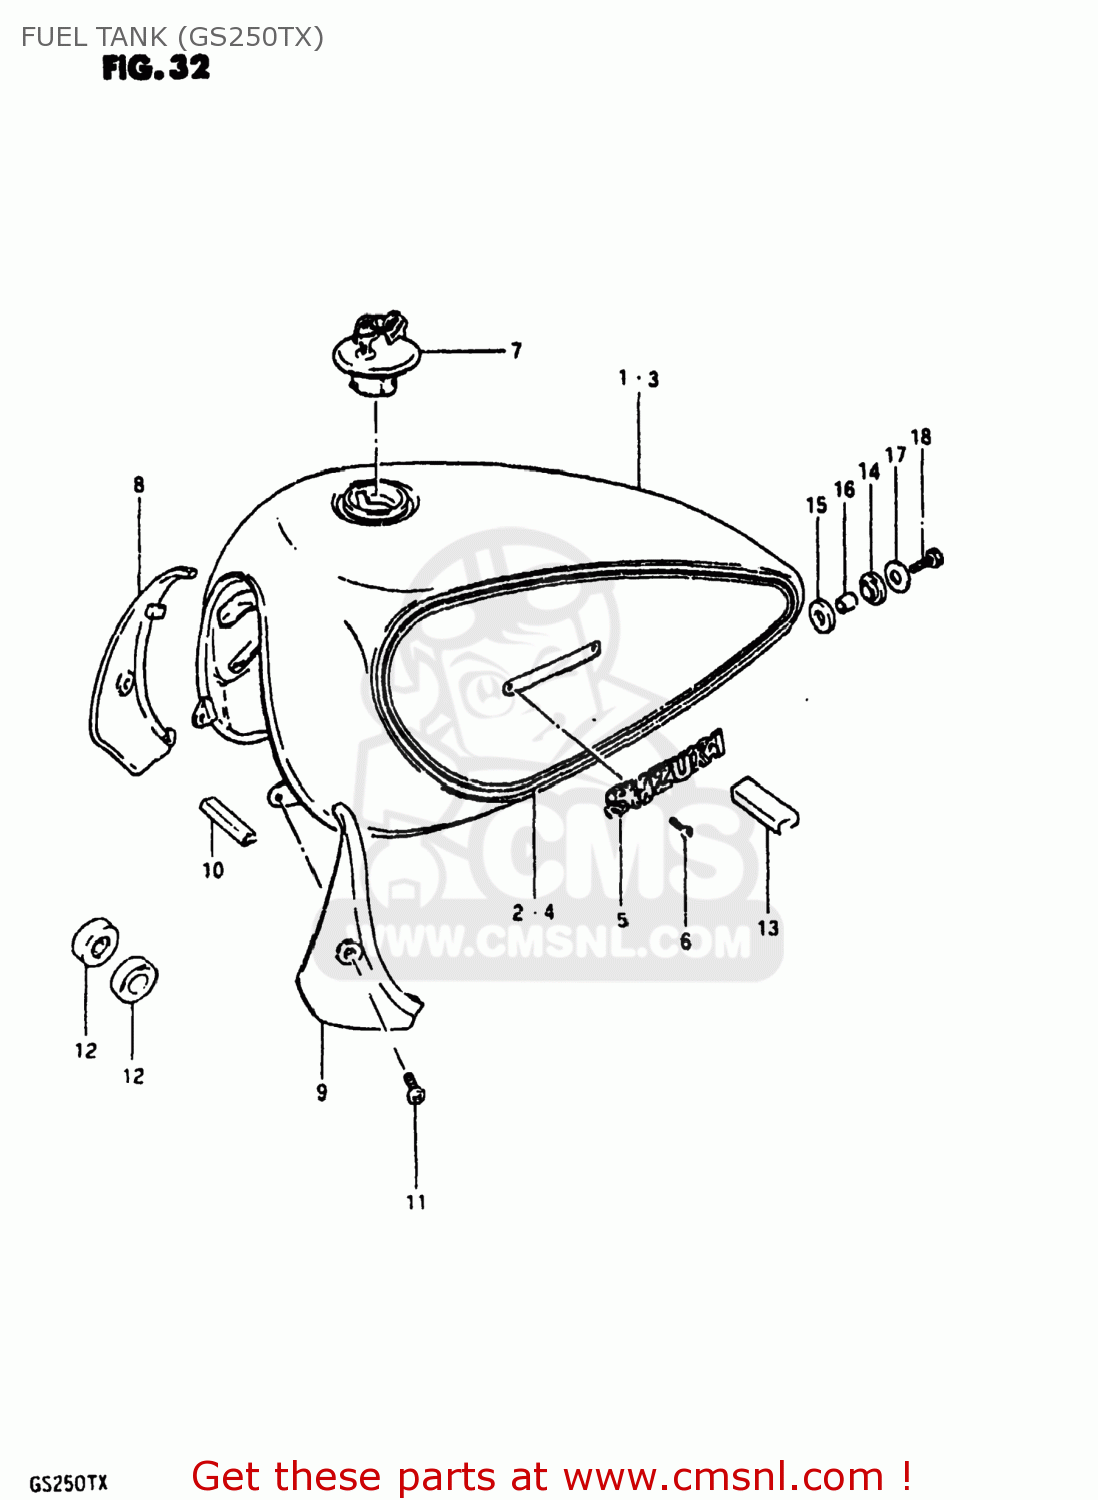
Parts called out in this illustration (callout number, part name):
1	TANK ASSEMBLY,FUEL
2	TAPE SET,FUEL TANK
3	TANK ASSEMBLY,FUEL
4	TAPE SET,FUEL TANK
5	EMBLEM,FUEL TANK
6	SCREW 3X6
7	CAP SET,FUEL TANK
8	COVER,FUEL TANK,FRONT,RIGHT
9	COVER,FUEL TANK,FRONT,LEFT
10	TUBE, FRONT
11	SCREW 6X12
12	CUSHION
13	CUSHION
14	CUSHION
15	CUSHION
16	SPACER(8.5X12X19)
17	WASHER (8.5X29X1.6)
18	BOLT (8X30)
